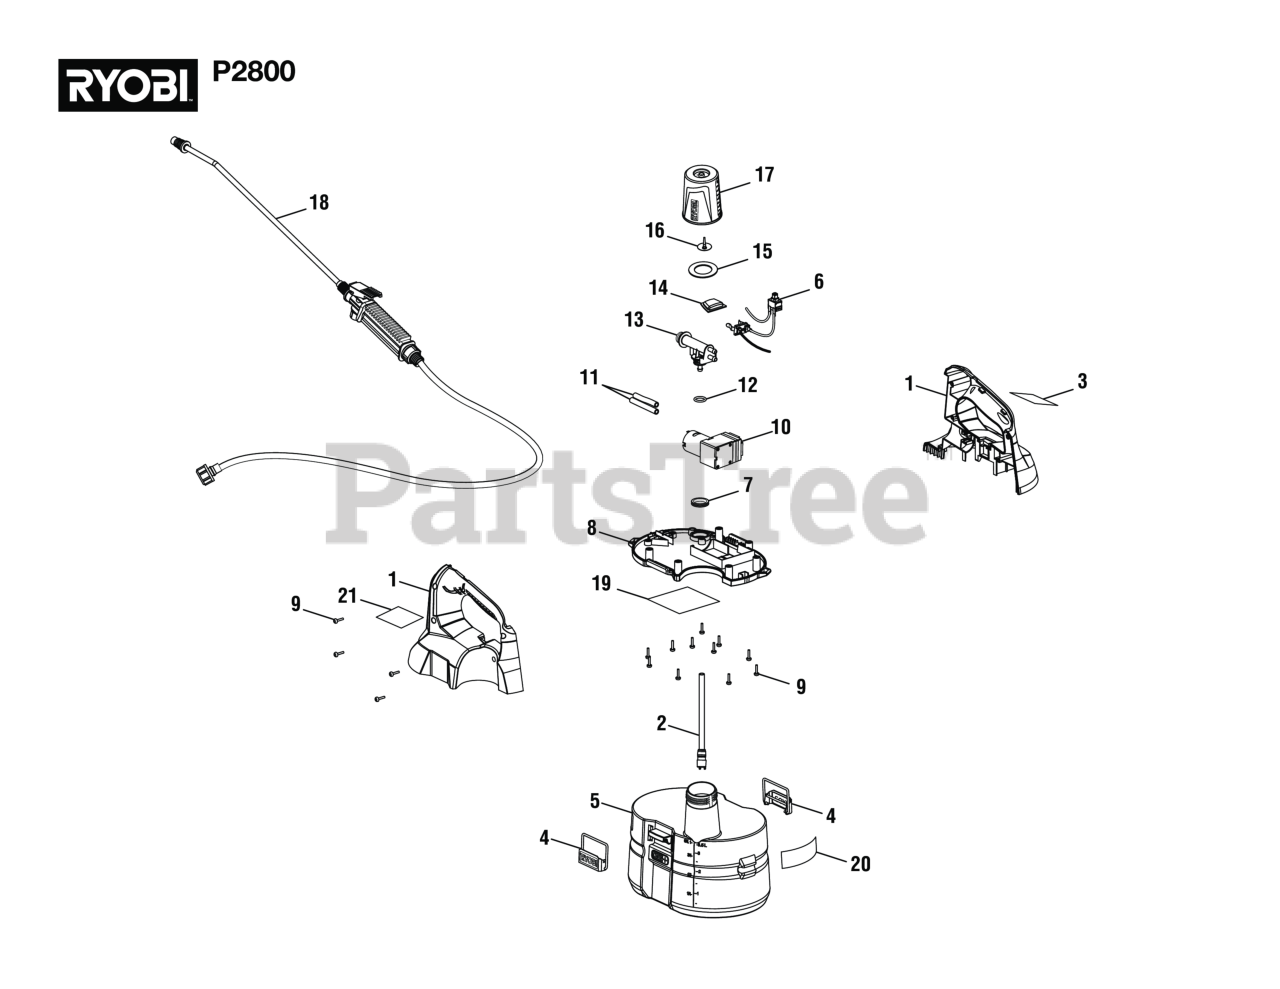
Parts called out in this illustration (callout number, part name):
1	Handle Housing Assembly
2	Suction Tube and Filter Assembly
3	Notice Label (B)
5	Water Tank Assembly
6	Wiring Harness and Switch Assembly
7	Rubber Seal
8	Housing Deck Assembly
9	Screw (M4x14 mm)
10	Pump Diaphragm Assembly
11	Tube (Short)
13	Connector
14	Switch Cover
15	Rubber Seal
16	Rubber Umbrella Pin
17	Tank Cap
18	Trigger Handle Assembly
19	Data Label
20	Warning Icon Label
21	Notice Label (A)
